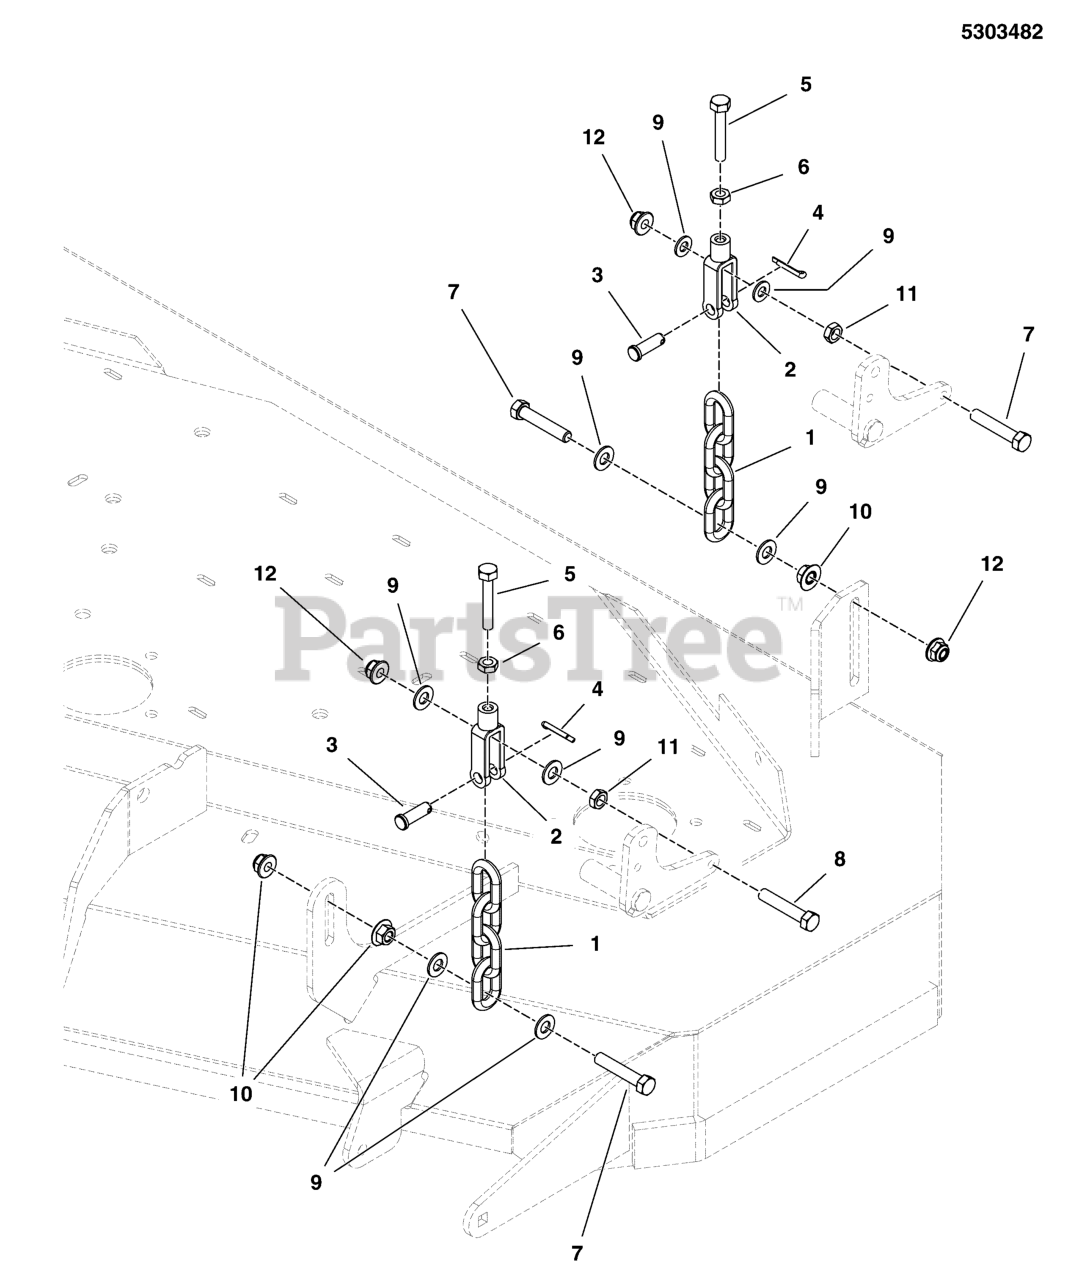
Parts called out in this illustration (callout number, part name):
1	CHAIN, 5/16" GD30, 4 LINKS
2	CLEVIS, 5/16-18, 3/8 PIN HOLE, CLR ZINC
3	PIN, CLEVIS, 3/8 X 1-1/8, PLATED
4	PIN, COTTER, 1/8 X 3/4
5	BOLT, 5/16-18 X 2 GD5 TFL
6	NUT, 5/16-18 HEX JAM
7	BOLT, 3/8-16 X 1-3/4" GD5 CZ
8	BOLT, 3/8-16 X 2, GD5, CZ
9	WASHER, 3/8 SAE
10	NUT, 3/8-16 HEX SERRATED FLANGE
11	NUT, 3/8-16 HEX JAM
12	NUT, 3/8-16 HEX NYLOCK FLANGE
